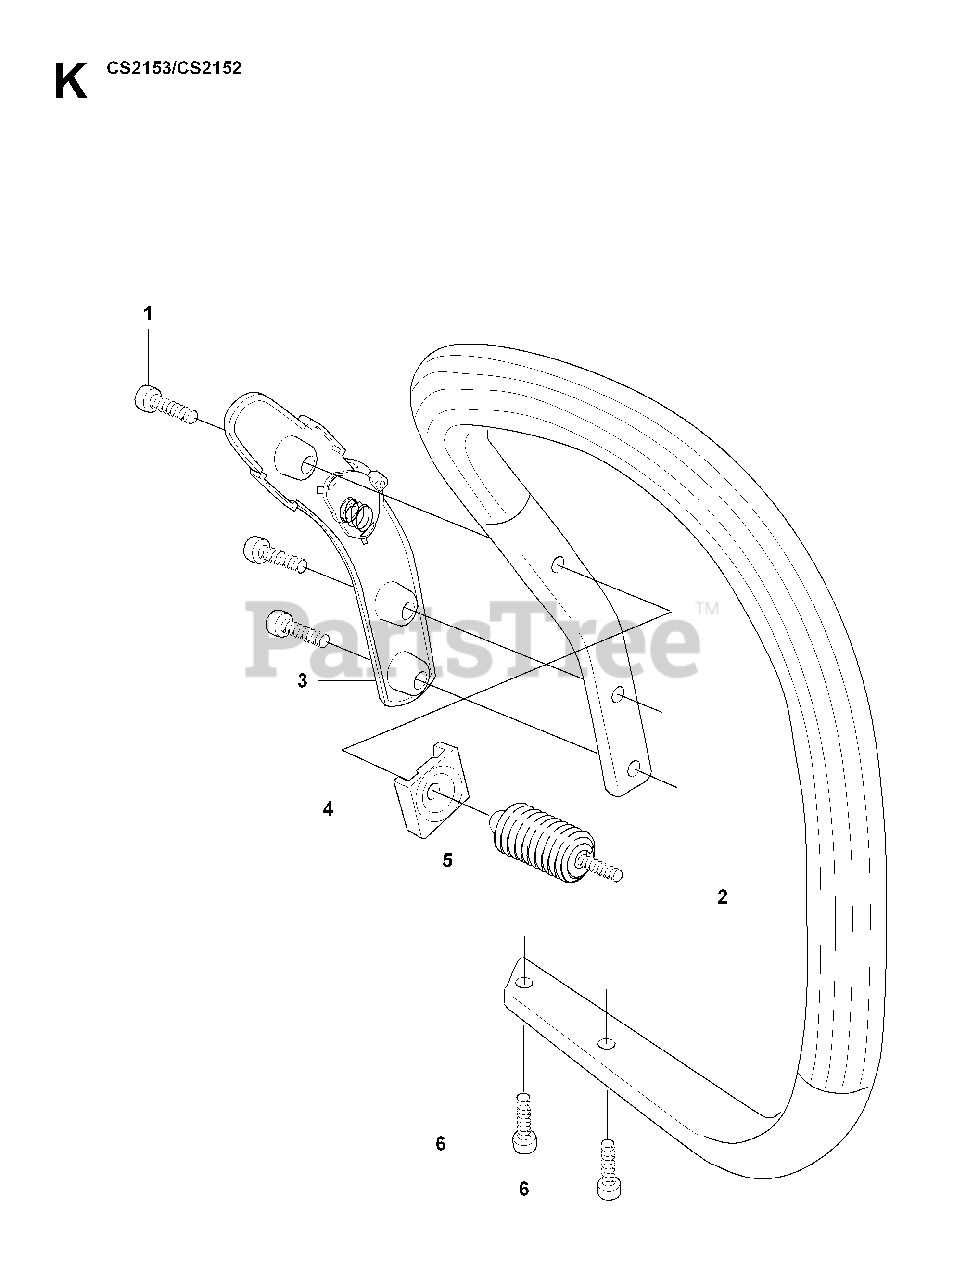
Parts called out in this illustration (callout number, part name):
2	FRONT HANDLE
5	INSULATOR
6	SCREW IHSCFT
